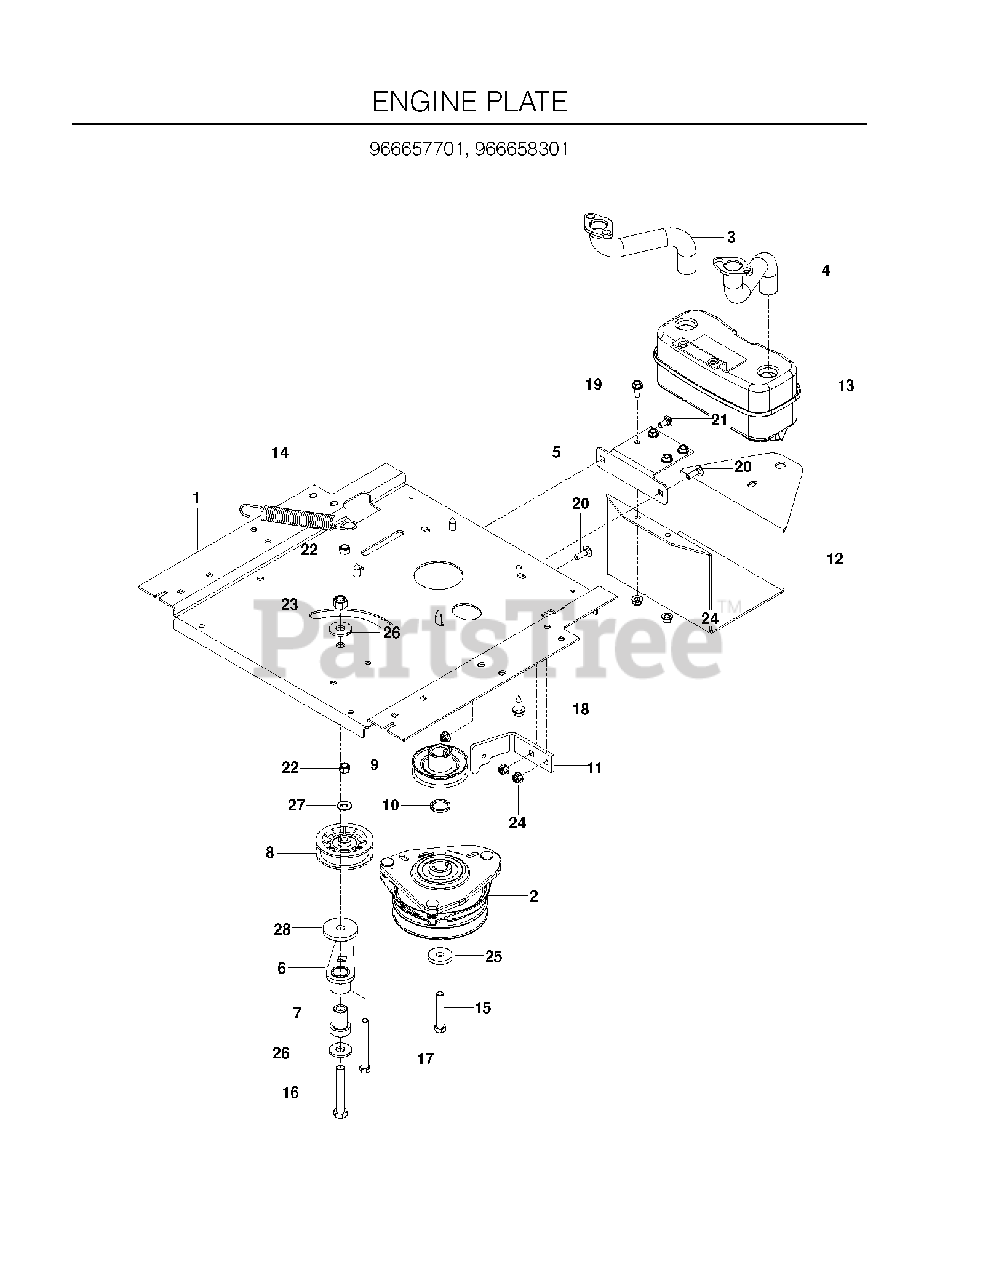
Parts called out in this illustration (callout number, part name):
1	PLATE, ENGINE BLK
3	TUBE MANIFOLD LH
4	EXHAUST TUBE RH
5	BRACKET, MUFFLER, BLACK
6	IDLER ARM
7	IDLER SPINDLE
8	PULLEY, IDLER
9	PULLEY, ENGINE
10	HUB PULLEY SPACER
11	CLUTCH STOP OGR BLK
12	GUARD, MUFFLER, BLACK
13	MUFFLER ASM TWIN
14	SPRING, DECK DRIVE
15	HCS 7/16-20 X 2.5 GR8
16	HCS 1/2C X 3 1/4
17	HCS 3/8-16X3 1/2 GR5
18	HHFS 3/8-16 X 1.0 THD FORMING
19	BOLT 5/16-18 X 3/4
20	RHSNB 5/16C X 1
21	BOLT 5/16C X 3/4" CARRIAGE
22	NUT 3/8-16 NYLOC
23	NUT 1/2-13 HEX NYLOC ZD
24	5/16-18 NYLOC FLANGE NUT
26	WASH USS FLAT 1/2
27	WASHER 5/16 FLAT
28	HEAVY WASHER
